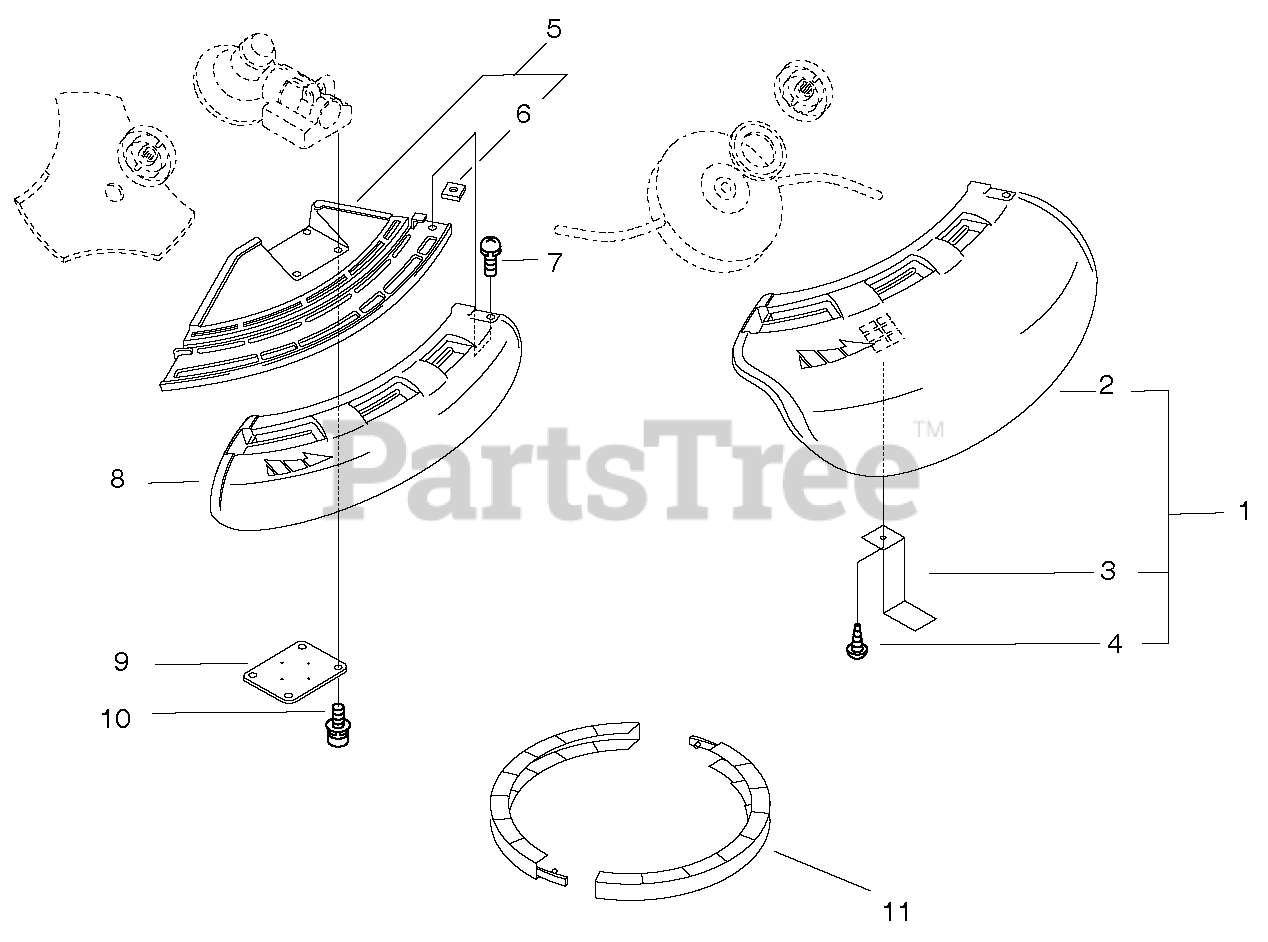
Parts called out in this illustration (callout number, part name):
1	DEBRIS SHIELD KIT - TRIMMER
2	SHIELD, DEBRIS - TRIMMER
3	KNIFE, TRIMMER LINE
4	SCREW - 5X12
5	SHIELD BRACKET ASSY
6	NUT - 5 -- SQUARE
7	SCREW - 5X22
8	SHIELD, DEBRIS - BLADE
10	BOLT - 5X25
11	COVER, BLADE
